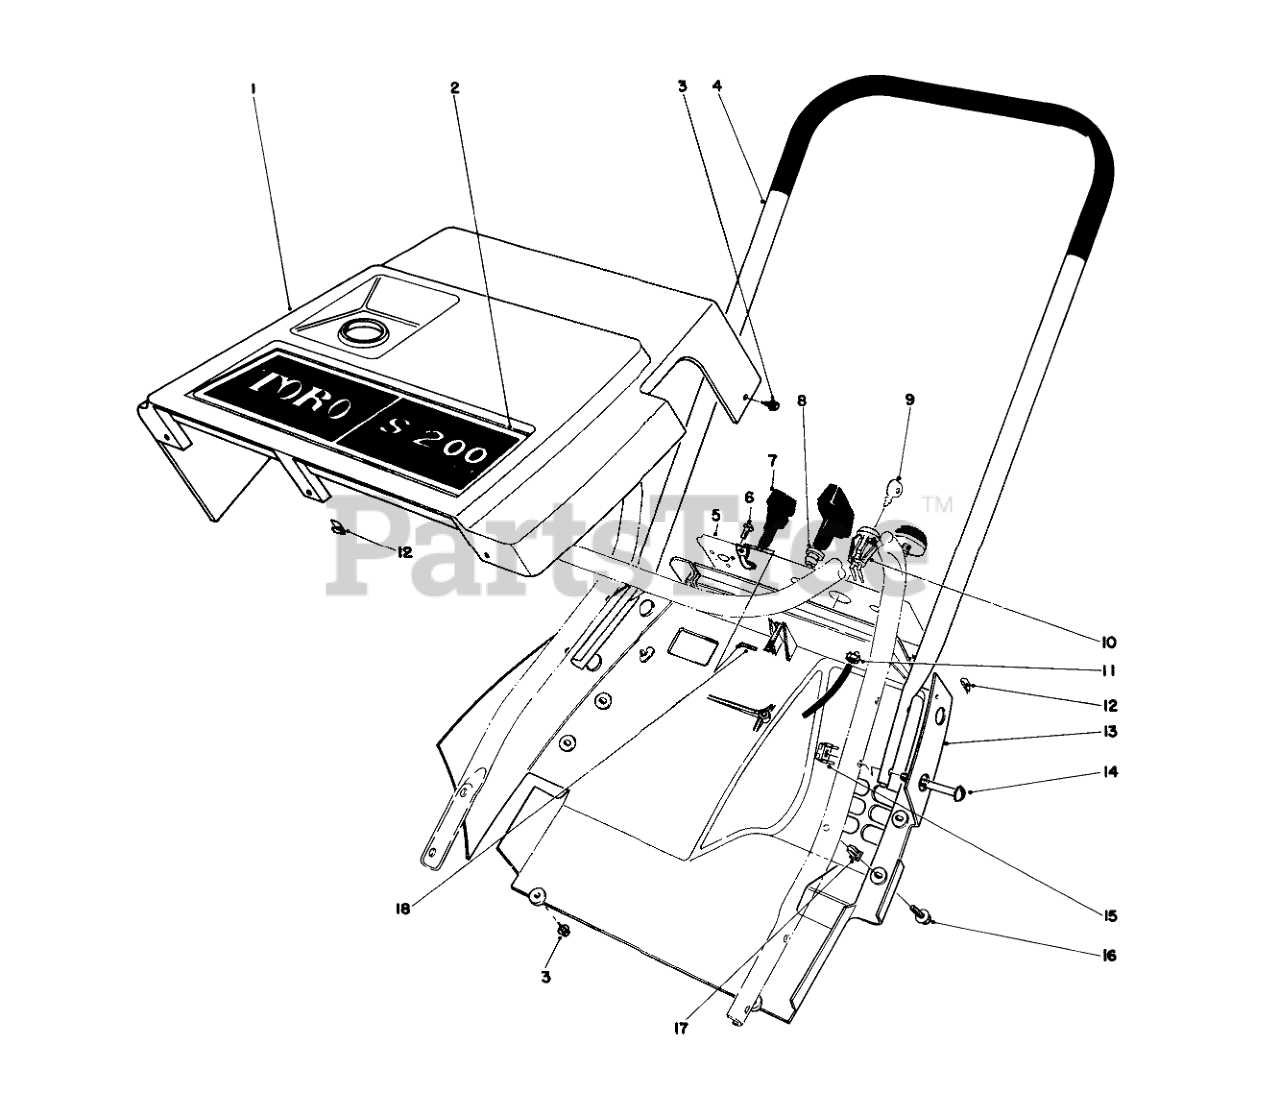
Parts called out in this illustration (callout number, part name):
1	Shroud-Upper
2	Decal-Toro
3	SCREW-HWHTF
4	Upper Handle
5	Cap-End
6	SCREW-PLASTITE
7	CHOKE CONTROL ASM
8	GUIDE-ROPE, STARTER
9	Key
10	SWITCH
11	Locknut
12	NUT-TYPE J
13	Lower Shroud
14	Sems Mach. Screw
15	TINNERMAN NUT
16	SCREW-HWHTF
17	PUSH IN NUT
18	CONTROL WIRE
